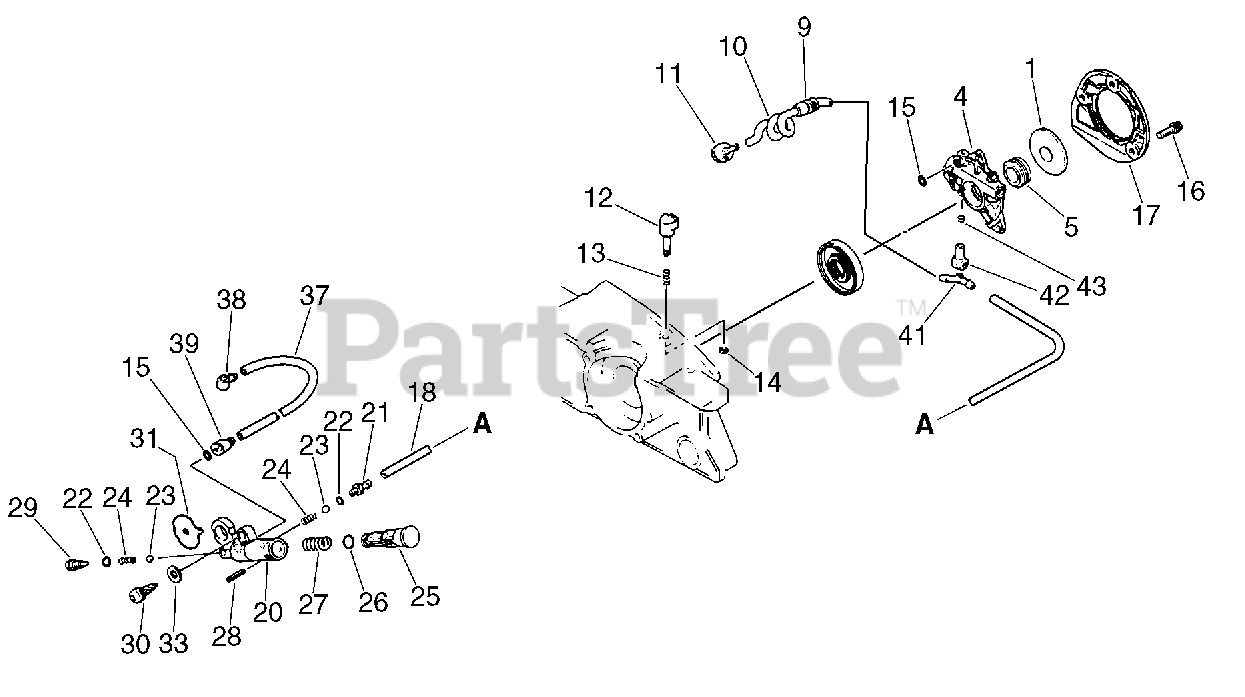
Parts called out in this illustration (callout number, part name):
4	AUTO-OILER ASSY
5	GEAR, WORM
10	PIPE, OIL
11	FILTER, OIL
14	E-RING 3
15	O-RING 3
16	BOLT 4×14
17	COVER, OIL PUMP - ORANGE
18	PIPE, FUEL 3×6×200
18	OIL PUMP ASSY
20	BODY, OIL PUMP
21	CONNECTOR, PIPE
23	VALVE, BALL
24	SPRING, VALVE
25	PISTON, OIL PUMP - BLACK
26	O-RING 7 MM
28	PIN, SPRING 2×16
29	ADAPTOR, OIL PUMP
30	SCREW 5×20
31	BRACKET, OIL PUMP
33	WASHER 5.5×12×0.8
37	PIPE 3×6×125 BLACK
38	CONNECTOR, PIPE
39	CONNECTOR, PIPE
41	CONNECTOR, PIPE
42	PIPE, OIL 3×6×20
43	CLIP 6.5 MM
